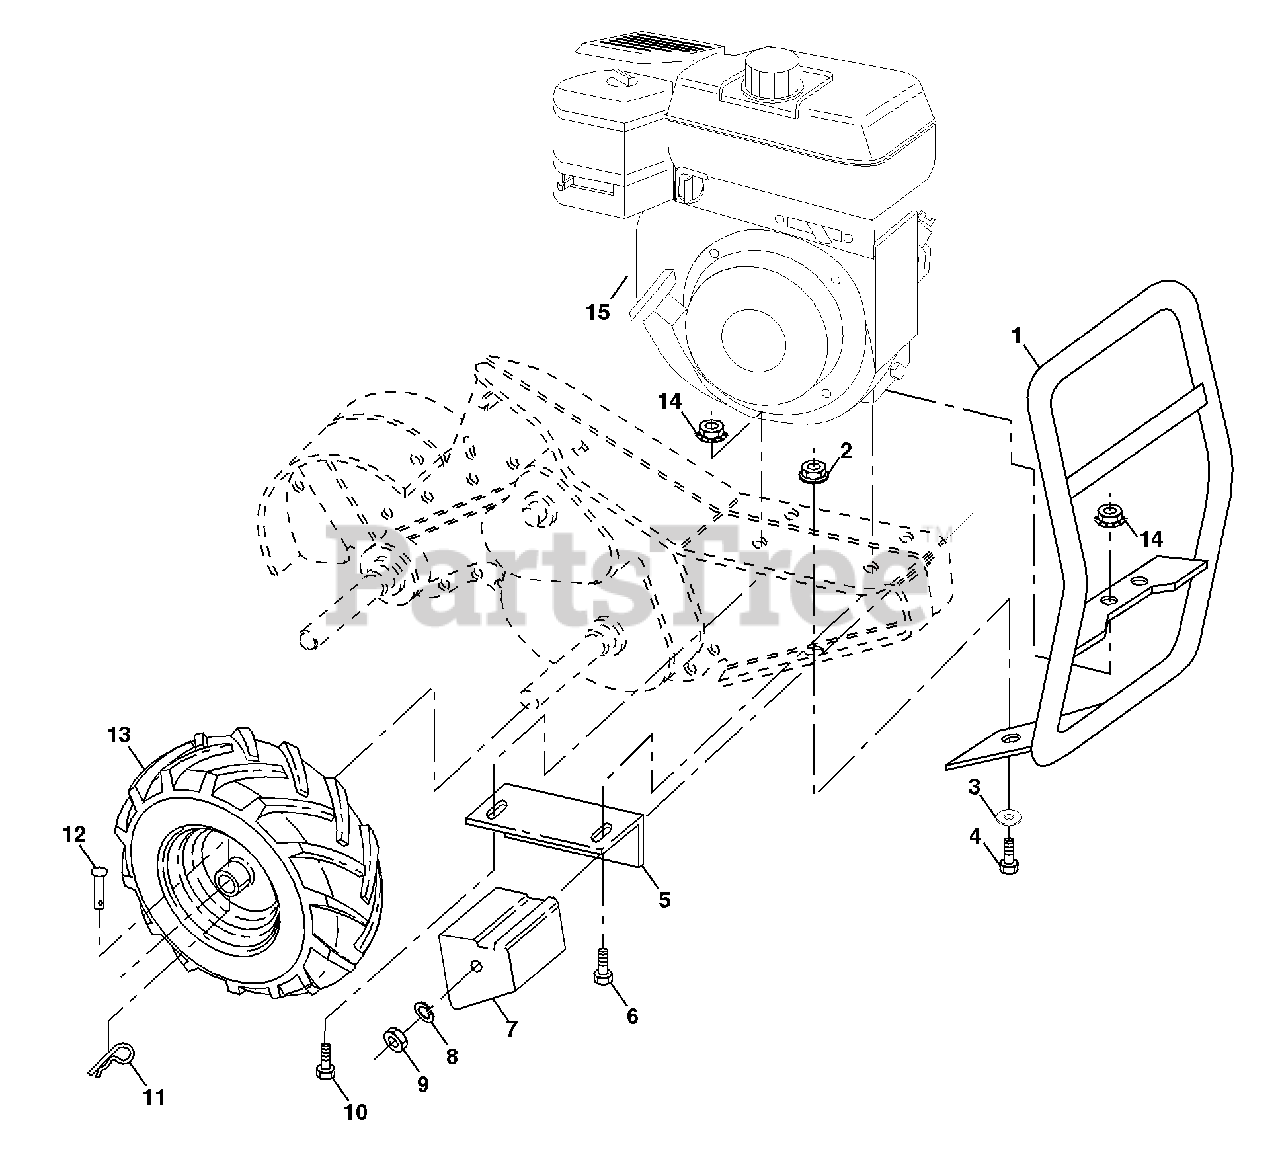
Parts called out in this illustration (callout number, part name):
1	Bumper
2	Locknut, Hex, Flange 5/16-18
3	Washer 11/32 x 11/16 x 16 Ga.
4	Bolt, Hex 5/16-18 x 3/4
5	Bracket, Reinforcement
6	Bolt, Hex 5/16-18 x 2
7	Counter Weight, R.H.
8	Washer, Lock 3/8
9	Nut, Hex 3/8-16
10	Bolt, Hex 5/16-18 x 1-1/2
11	Clip, Hairpin
12	Rivet, Drilled
13	Rim
13	Tire Valve
14	Nut, Lock, Hex Flange
